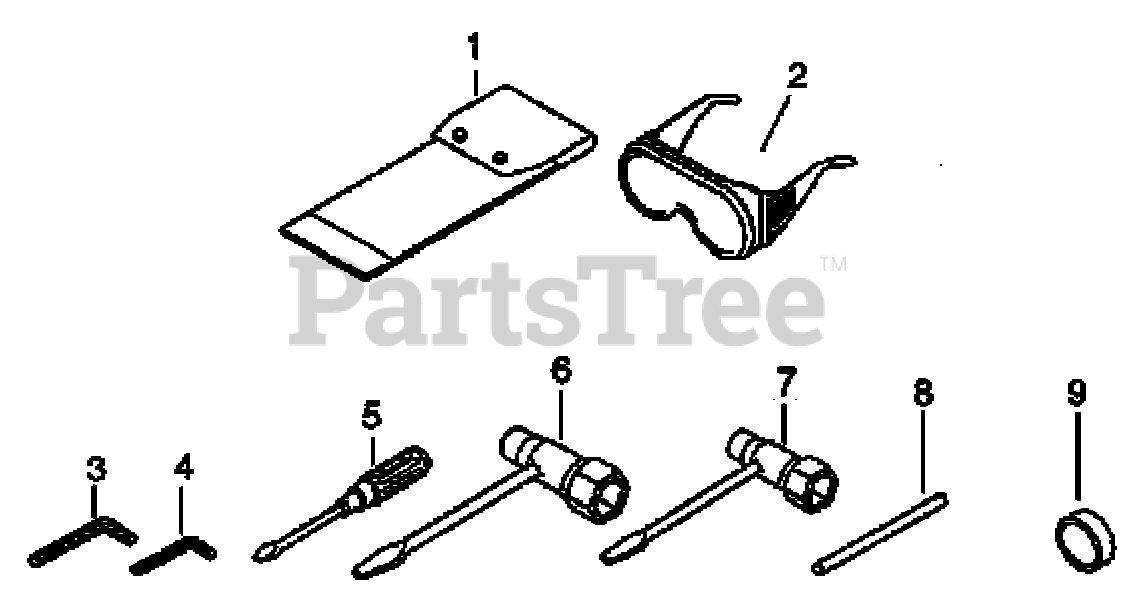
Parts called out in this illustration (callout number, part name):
1	BAG, TOOL
2	GLASSES, SAFETY
3	WRENCH, ALLEN 4 MM
4	WRENCH, ALLEN 3 MM
5	SCREWDRIVER, SLOTTED
6	WRENCH, T 17×19 MM
7	T-WRENCH 13×19×180
8	TOOL, LOCKING 5×120 MM
9	COLLAR 20
